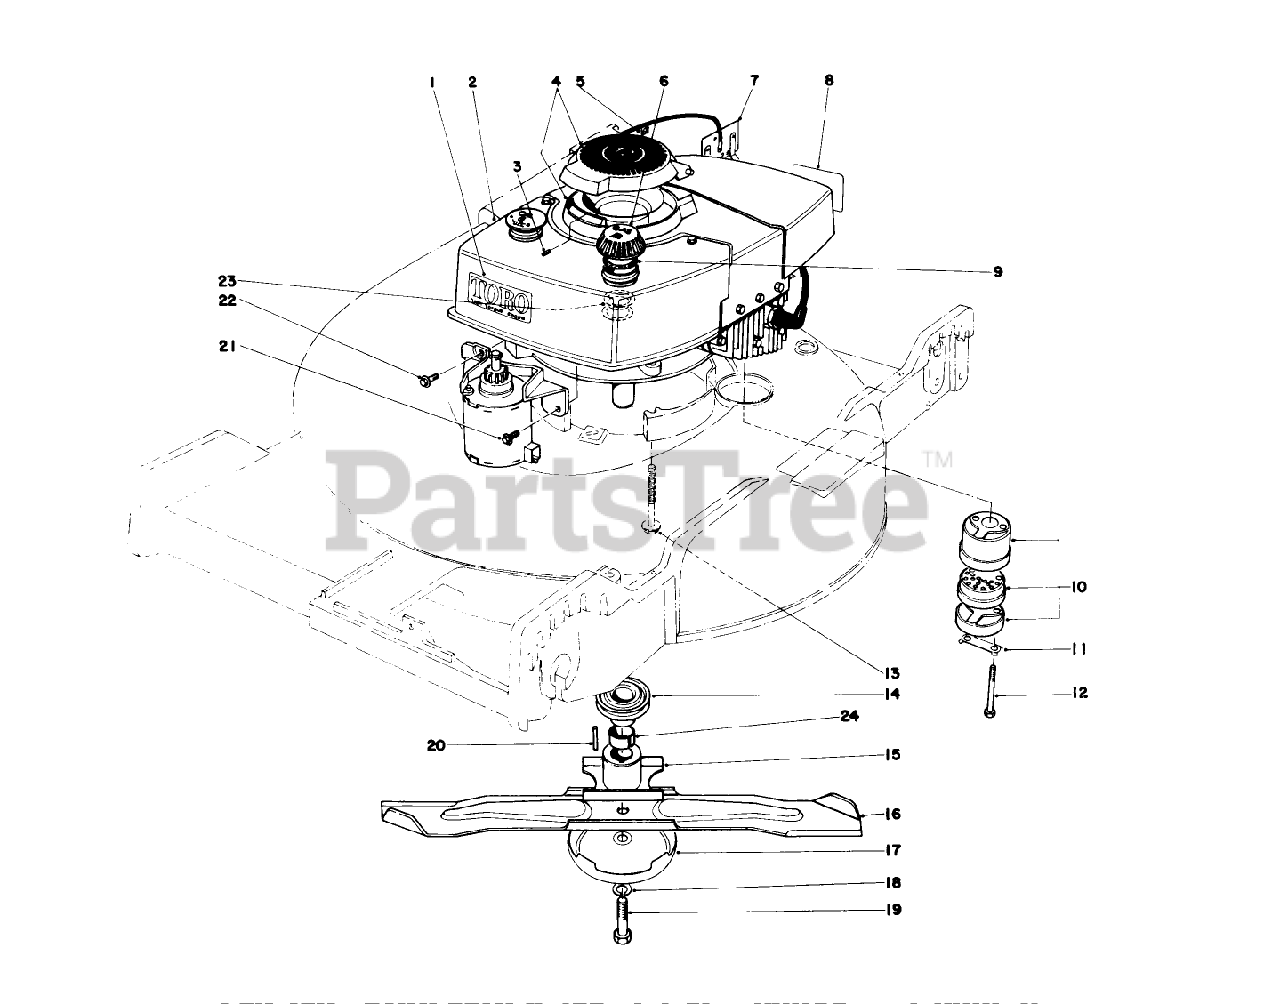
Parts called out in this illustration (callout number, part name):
2	Engine
3	SPRING PIN
9	GASKET
10	MUFFLER ASM
11	CLIP - LOCKING
12	SCREW-HH
13	3/8-16 X 2-3/4 CAPSCR
15	BLADE RETAINER WA
18	WASHER-LOCK
19	BLADE SCREW
20	KEY-SQUARE
21	SCREW
